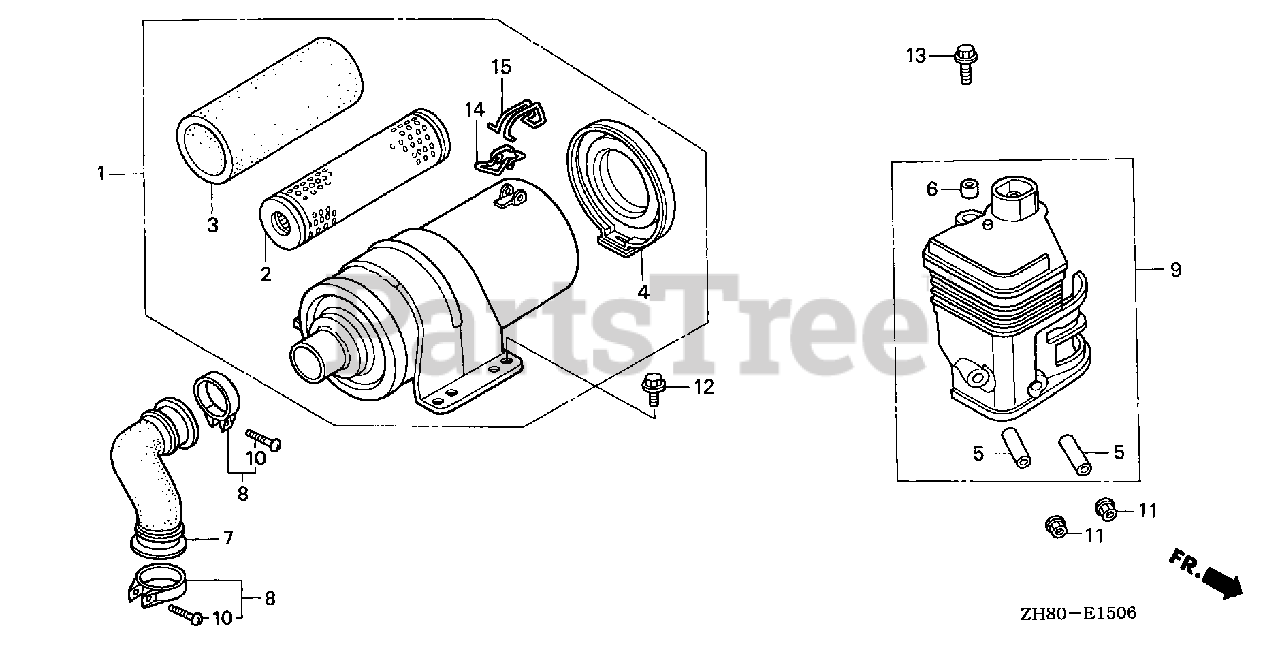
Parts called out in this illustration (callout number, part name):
1	AIR CLEANER ASSY.
2	ELEMENT, AIR CLEANER
3	FILTER (OUTER)
4	COVER, AIR CLEANER
5	COLLAR, AIR CLEANER
6	COLLAR B, AIR CLEANER
7	TUBE, AIR CLEANER CONNECTING
8	BAND, AIR CLEANER CONNECTING TUBE
9	ELBOW, AIR CLEANER
10	SCREW, PAN (4X20)
11	NUT, FLANGE (6MM)
12	BOLT, FLANGE (6X16)
13	BOLT, FLANGE (6X20)
14	CLIP A, WIRE
15	CLIP B, WIRE
